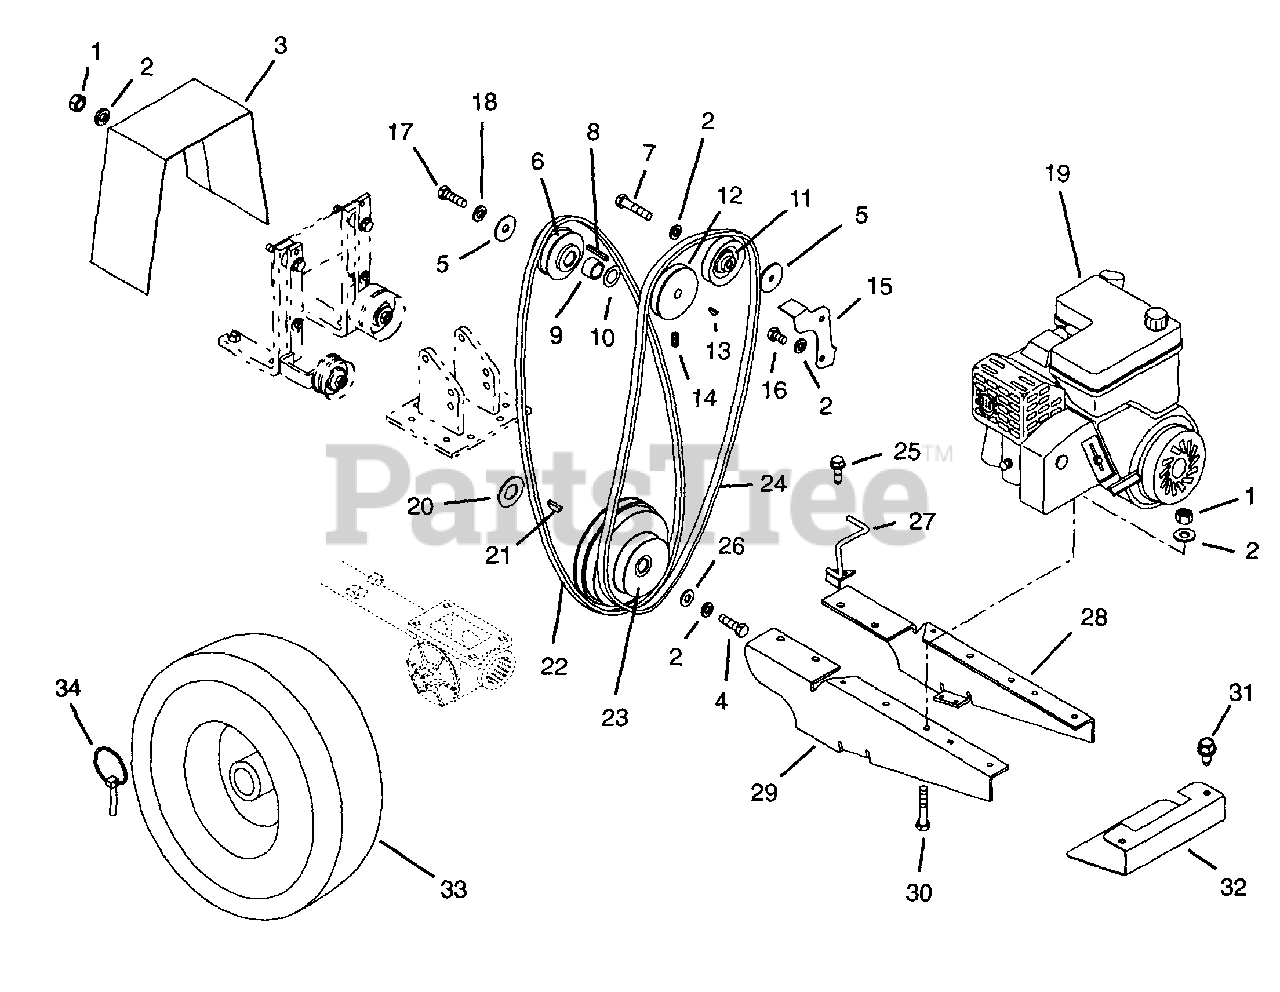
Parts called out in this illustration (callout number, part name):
1	@NUT-HEX .31-18 YWZC
2	@WSHR-LK .31X.078 REG YWZC
3	BELT GUARD W/DECALS
4	@BLT-HEX .31-18X1.00 GR5 YWZC
5	@WSHR-FL-STL.38X.875X.083 YWZC
6	SHEAVE, FORWARD
7	BLT-HEX .31-24X1.50 GR5 YWZC
8	KEY-SQ .188X1.5X.187 SAE 8630
9	SPACER .765X.875X.870
10	WSHR-HDND-THRST .758X1.23X.031
11	IDLER-V 2.625X.312
12	SHEAVE REVERSE OHH50
13	KEY-WDRF .125X.625X.250 SAE5
14	SCR-SET .25-20X.38 SKHCUPNL OH
15	BELT FINGER
16	SCR-CAP .31-24X.50HH GR5 YWZC
17	BLT-HEX .31-24X1.00 GR5 YWZC
18	@WSHR-LK .31X.078 REG YWZC
19	5HP TEC OHH50 W/2:1
20	WSHR-FL-STL .699X1.375X.059
21	KEY-WDRF .188X.75X.313 SAE 9
22	V-BELT, 4L-WRAPPED
23	SHEAVE - TRANSMISSION
24	V-BELT, 3L-WRAPPED
25	SCR-TAP .25-20X.75 HWH TR YWZ
26	WSHR-FL-STL .328X.87X.179 YWZC
27	BELT FINGER WELDMENT
28	L H ENGINE MTG BRKT
29	R H ENGINE MTG BRKT
30	@BLT-HEX .31-18X1.75 GR5 YWZC
31	@SCR-TAP .31-18X.50 HWH TR YWZ
32	COVER, ENGINE BRKT
33	T/WHL ASSY RH
34	PIN-LOK .31X2.00
